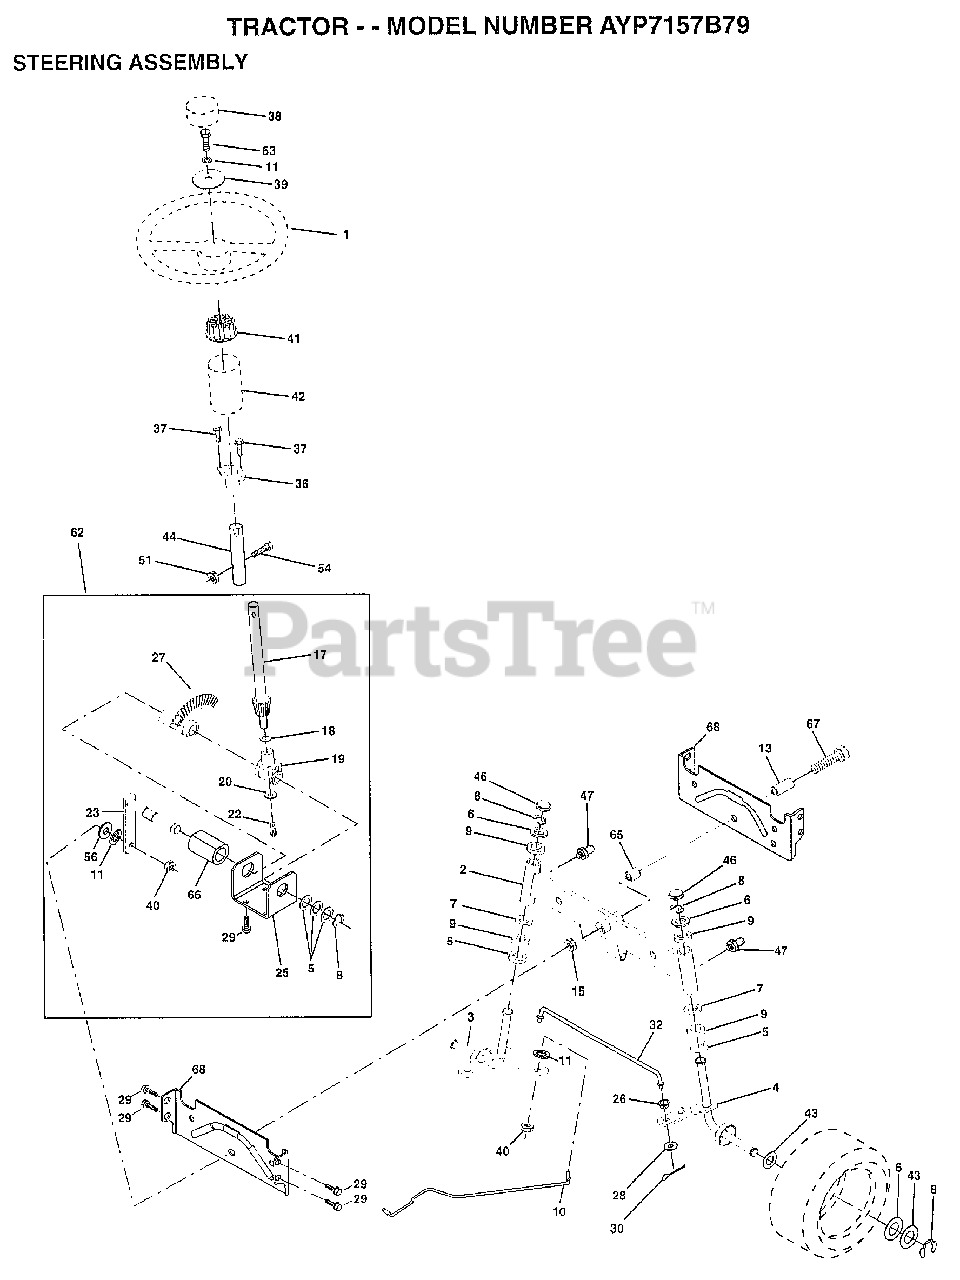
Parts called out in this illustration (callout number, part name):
1	WHEEL STR AYP BLK
2	AXLE ASM
3	SPINDLE.ASM.LH
4	"SPINDLE ASM,RH"
5	WASHER .T
6	WASHER
7	WASHER
8	RING
9	COL. SRTG. BEAR.
10	DRAGLINK-STAMPED
11	LOCKWASHER
13	BEARING AXLE
15	"NUT-LOC,FLANGE LT"
17	SHAFT ASM STEERIN
18	THRUST WASHER
19	SUPPORT.SHAFT
21	LOCKWASHER
22	SCREW.SCKTHD.CAP
25	BRKT-STEERING
26	BUSHING.DRAGLINK
27	GEAR SECTOR
28	WASHER
29	SCREW
30	COTTER PIN
32	TIE ROD
36	BUSHING.STEERING
37	"SCREW-TT,10-32 FL"
38	CAP STEER AYP
39	WASHER T
40	GRIPCO NUT
41	ADAPTER LT
42	BOOT.STEER.PL
43	WASHER
44	EXT SHAFT STEERIN
46	CAP
47	ZERK M
51	NUT
54	BOLT
55	CLIP TINNERMAN
62	KIT STEERING ASM
63	BOLT
65	SPACER AXLE
66	"BEARING-ARM,PITMA"
67	BOLT
68	BRACE AXLE
